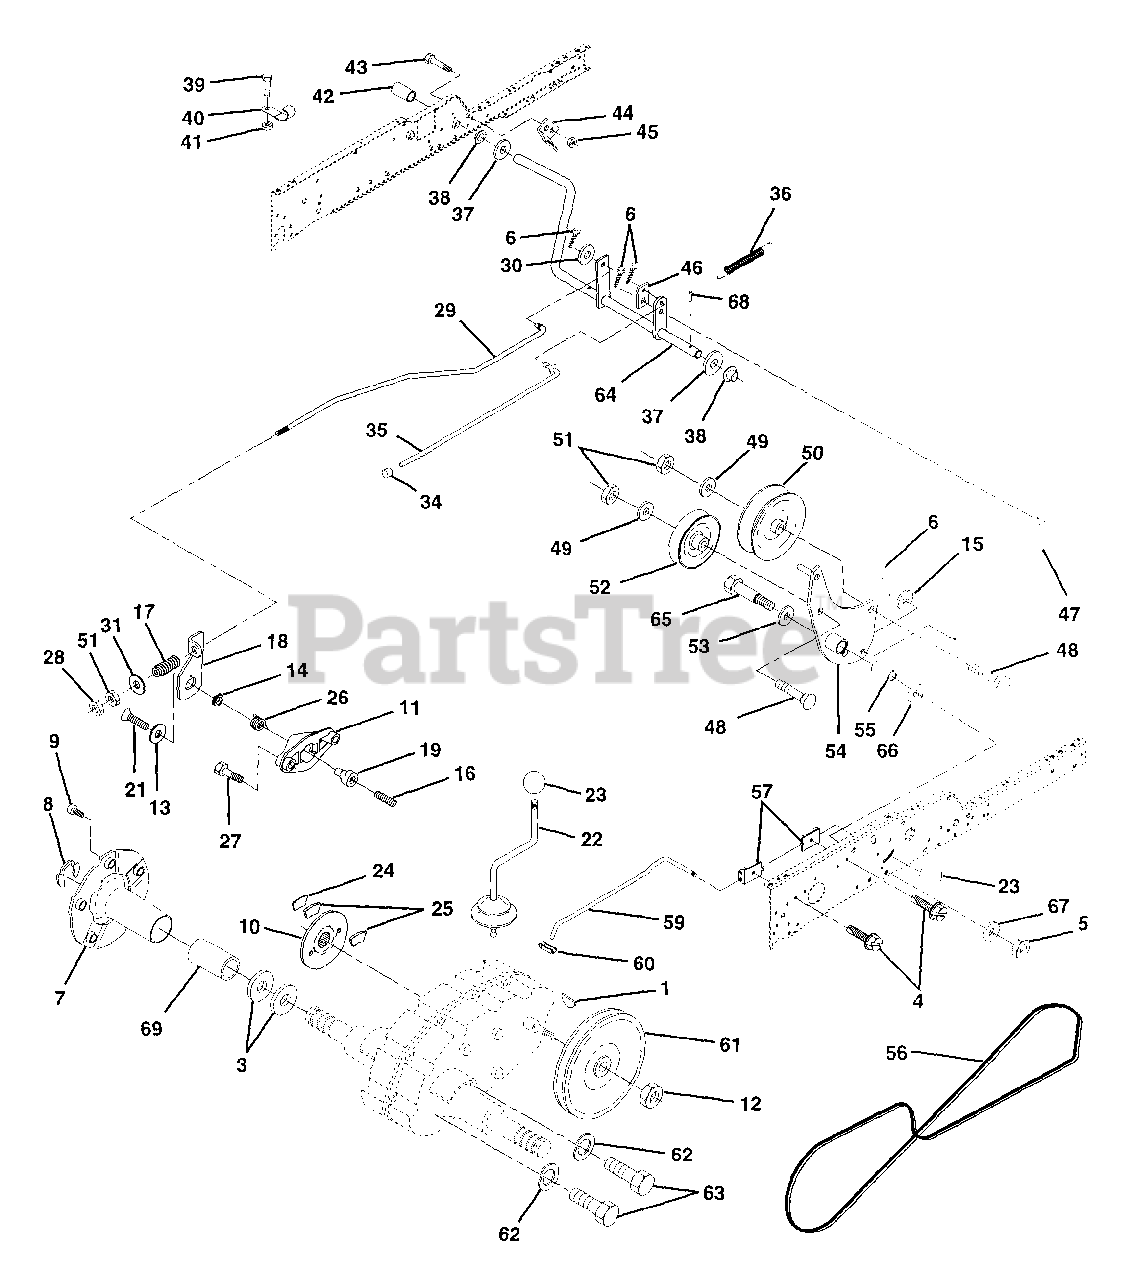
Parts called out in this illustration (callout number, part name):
1	Key Woodruff
3	Washer Thrust Axle Harden
4	Screw Thdrol 5/16-18 x 1/2 TYT
5	Nut Crownlock 3/8-16
6	Pin Cotter 1/8 x 3/4
7	Wheel Hub Asm.
10	Disc Brake
11	Yoke Brake Disc
12	Locknut 1/2-20
13	Washer Special
15	Washer 13/32 x 13/16 x 16 Ga
16	Set Screw 1/4-28 x 3/4
18	Lever Brake
19	Cam Brake Disc
21	Screw Flat Head 1/4-28 x 3/4
22	Gearshift Lever Assembly
24	Support Puck Brake
25	Puck Brake Top
26	Spring Return
27	Screw Hex Wsh Thd 5/16-18 x 1-3/4
28	Nut Hex Jam 3/8-16
31	Washer 13/32 x 1 x 16 Ga
34	Cap Plunger
35	Rod Parking Brake
36	Spring Extension
37	Washer 25/32 x 1-1/4 x 16 Ga
39	Screw Fin #10-24 x 1
40	Actuator Interlock Switch
41	Nut Lock #10-24
42	Cover Pedal
43	Bolt Hex Head 1/4-20 x 3/4
44	Bracket Interlock
45	Nut Lock W/Insert 1/4-20
46	Retainer Spring
47	Clutch Rod
48	Bolt Carriage 3/8-16 x 1-3/4 Gr 5
49	Washer 13/32 x 7/8 x 13 Ga
50	Pulley Idler Flat
51	Nut, Crownlock 3/8-16 Unc
52	Pulley Idler Grooved
53	Washer Hardened
54	Clutch Arm Asm
55	Bearing, Idler
57	Bracket Shift Rod Hi-Lo
59	Shift Rod Hi-Lo
60	Spring Clip Connecting Link
61	Pulley Transaxle
62	Washer Lock 7/16
63	Bolt Fin Hex 7/16-14 x 1-1/4
64	Shaft Clutch/Brake Pedal
65	Bolt Shoulder
66	Washer Hardened
67	Washer 13/32 x 13/16 x 12 Ga.
